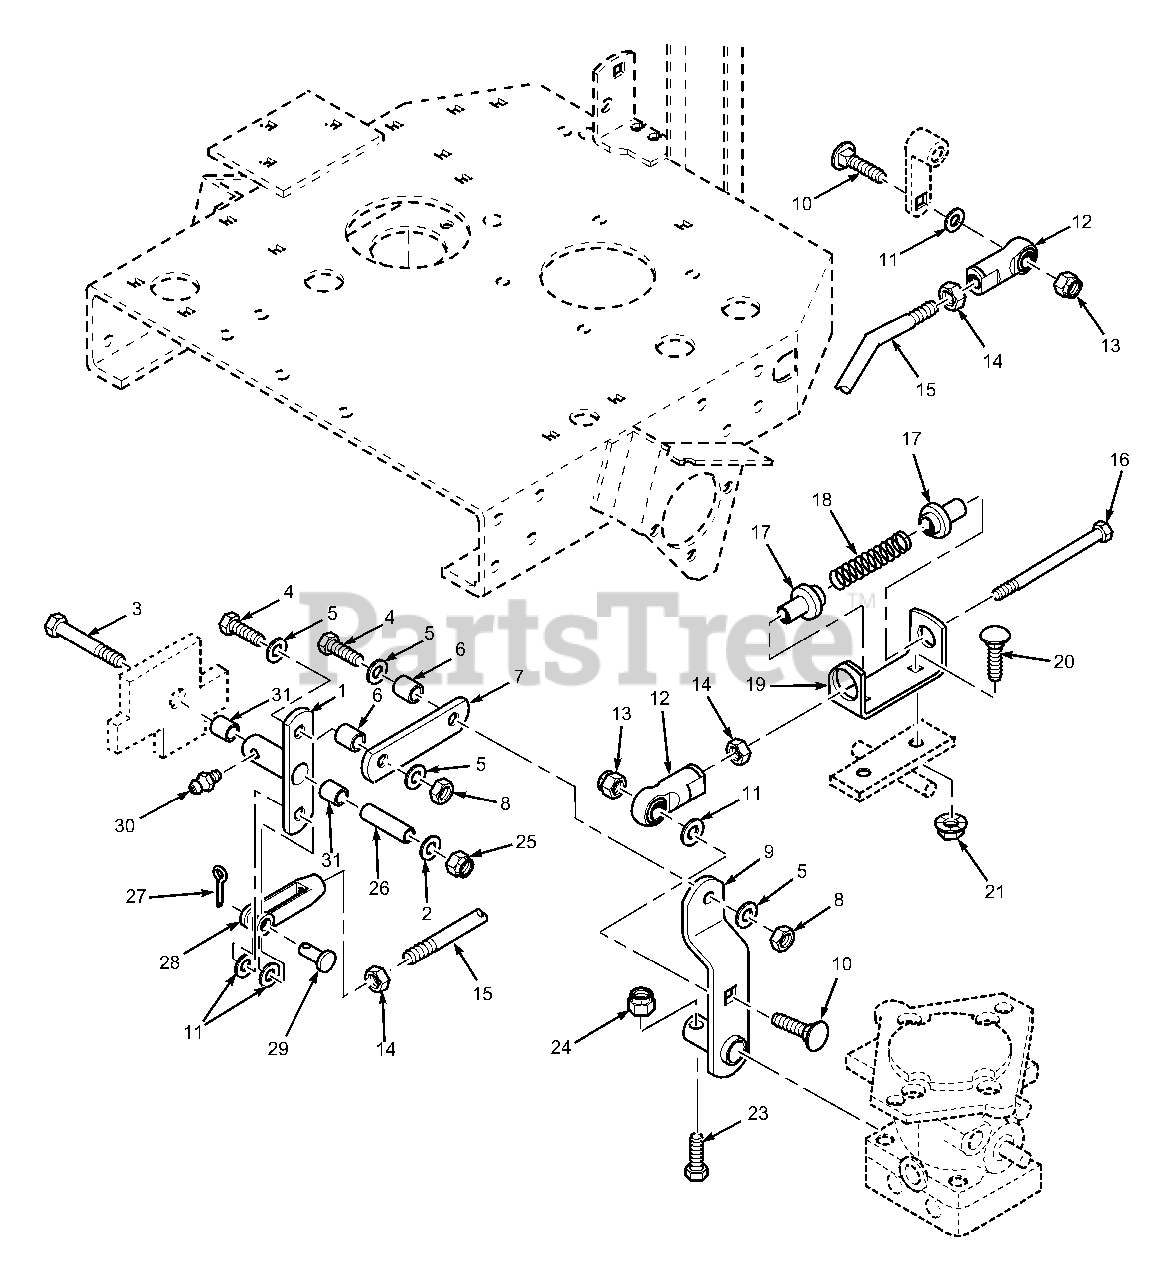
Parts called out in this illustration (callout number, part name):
1	Control Linkage, Bellcrank
2	Flatwasher, 5/16 (.375 x .875 x .083)
3	Bolt, Hex Head 5/16-18 x 2-3/4"
4	Bolt, Hex Head 3/8-16 x 1"
5	Flatwasher, 3/8 (.406 x .812 x .065)
6	Sleeve, Pump Control Link
7	Link, Speed Control
8	Hex Locknut, 3/8-16
9	Control Arm, Pump
10	Carriage Bolt,RH SH SQNK 3/8-16 x 1-1/2"
11	Flatwasher, 3/8 (.391 x .938 x .105)
12	Rod End, RH Female THD 3/8-24
13	Hex Locknut, Elastic Stop 3/8-16
14	Hex Nut, 3/8-24
15	Control Rod
16	Bolt Hex Head, 3/8-24 x 6-3/4"
17	Bushing, Spring Keeper
18	Spring, Neutral Return
19	Retainer, Neutral Spring
20	Carriage Bolt, 5/16-18 x 1"
21	Serr. Fl. Hex Nut 5/16-18
23	Bolt, Hex Head 1/4-20 x 1-1/4"
24	Hex Locknut, Elastic Stop 1/4-20
25	Hex Locknut, Elastic Stop 5/16-18
26	Sleeve, Control Arm
27	Cotter Pin, 3/32 x .75"
28	Clevis, Pump Control
29	Pin, Clevis 3/8"
30	Greese Fitting, 1/4-28 Self Tap
31	Bushing, Bronze
